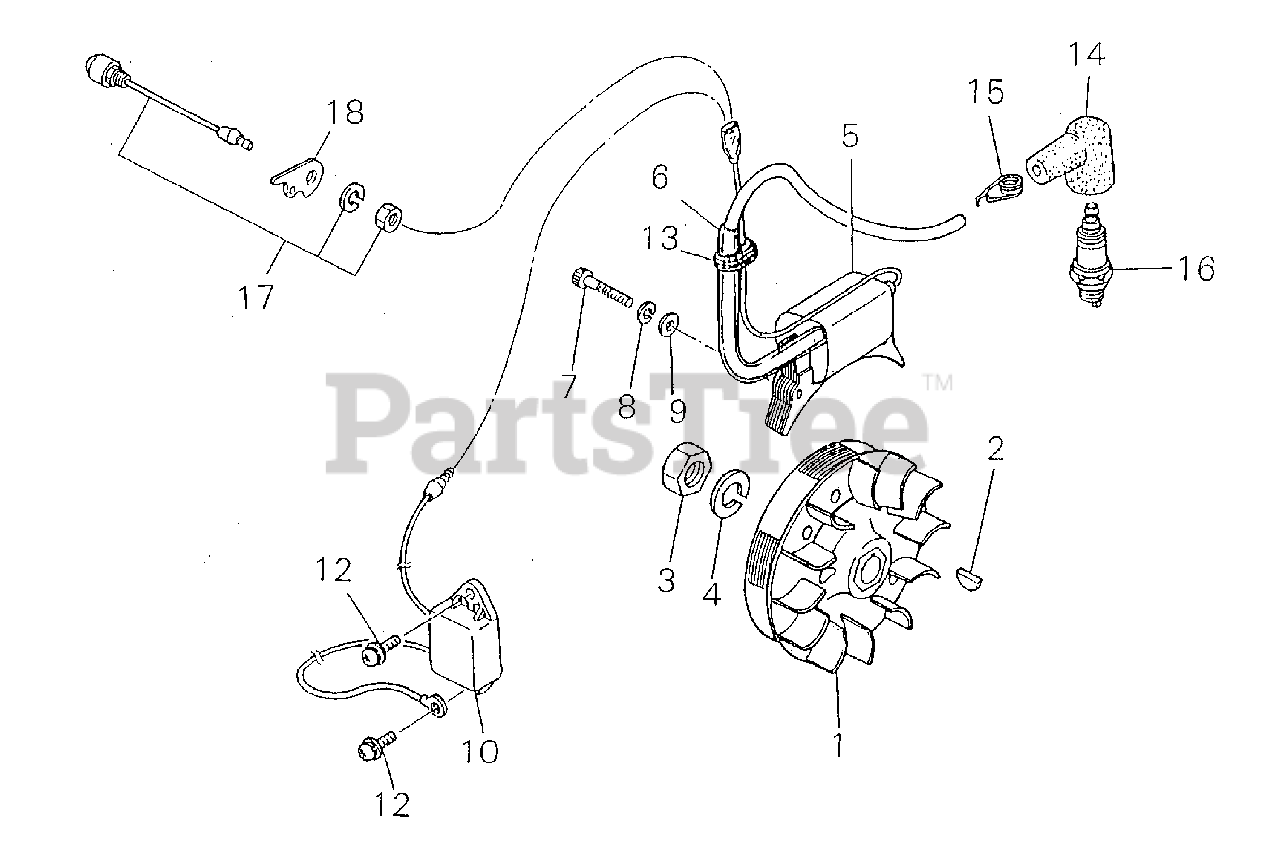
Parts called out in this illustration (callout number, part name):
1	FLYWHEEL
2	KEY - 3X10
3	NUT
4	LOCKWASHER - 8
5	COIL
6	TUBE - VINYL
7	SCREW - 4X24
8	LOCKWASHER - 4
9	WASHER - 4
10	UNIT, ELECTRONIC
12	SCREW - 4X12
14	CAP, SPARK PLUG
15	TERMINAL, SPARK PLUG CAP
16	SPARK PLUG -- CJ8
17	SWITCH, IGNITION
18	BRACKET
